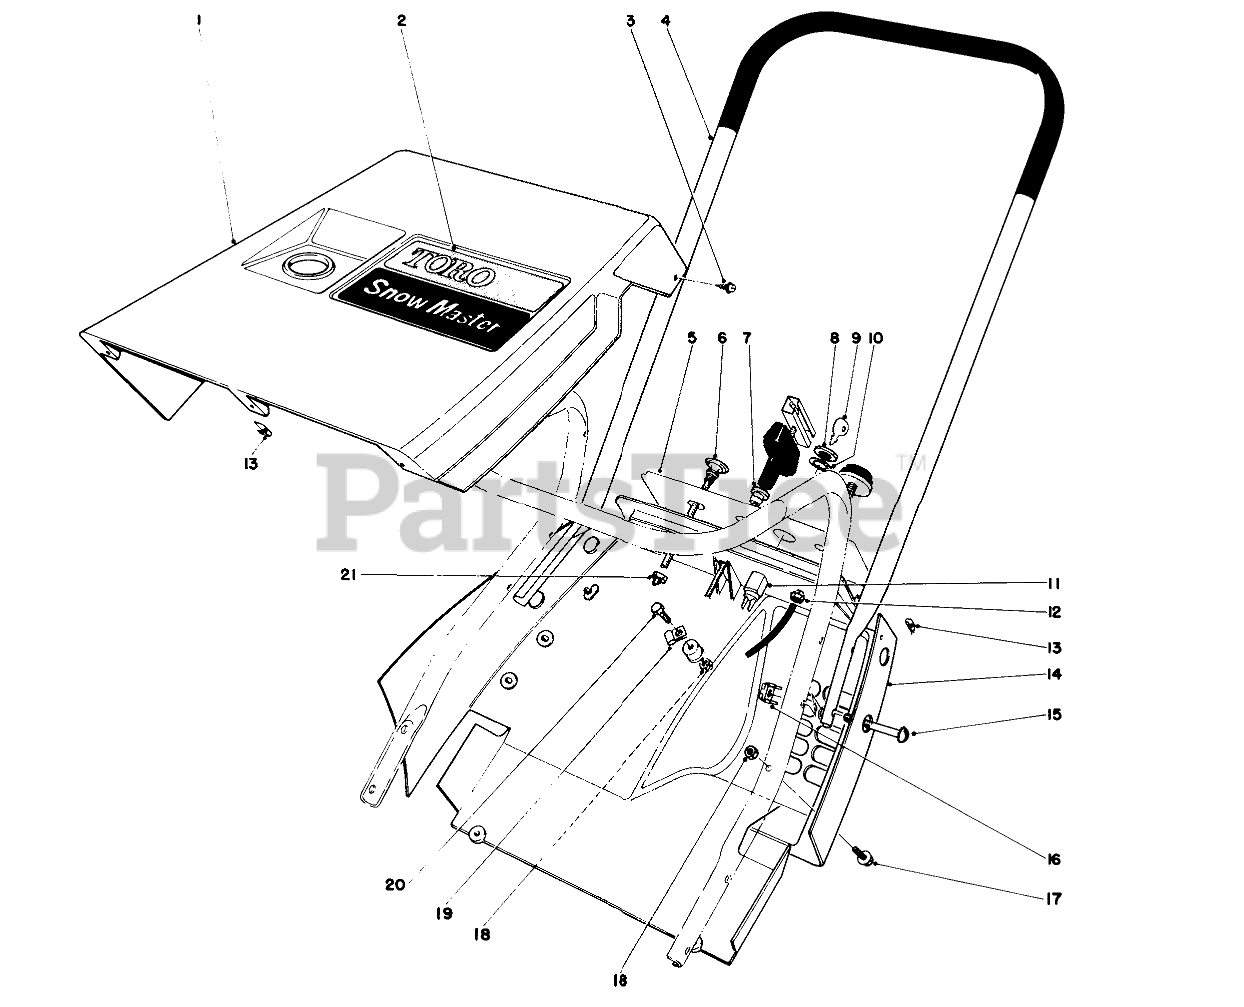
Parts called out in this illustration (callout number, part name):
1	Upper Shroud
2	Decal Toro
3	SCREW-HWHTF
4	Upper Handle
5	Decal-Central Panel
6	Choke Cable
7	GUIDE-ROPE, STARTER
8	NUT-HH
9	Ket (set of 2)
10	WASHER-TOOTH, INTERNAL
11	Switch
12	NUT-KEPS
13	NUT-TYPE J
14	Lower Shroud (Incl. Ref. #5)
15	Sems Mach. Screw
16	TINNERMAN NUT
17	Screw Special
18	NUT-LOCK, NI
19	3/16 SUPPORT
20	SCREW-HWH
21	PAL NUT/CHOKE CNTRL
